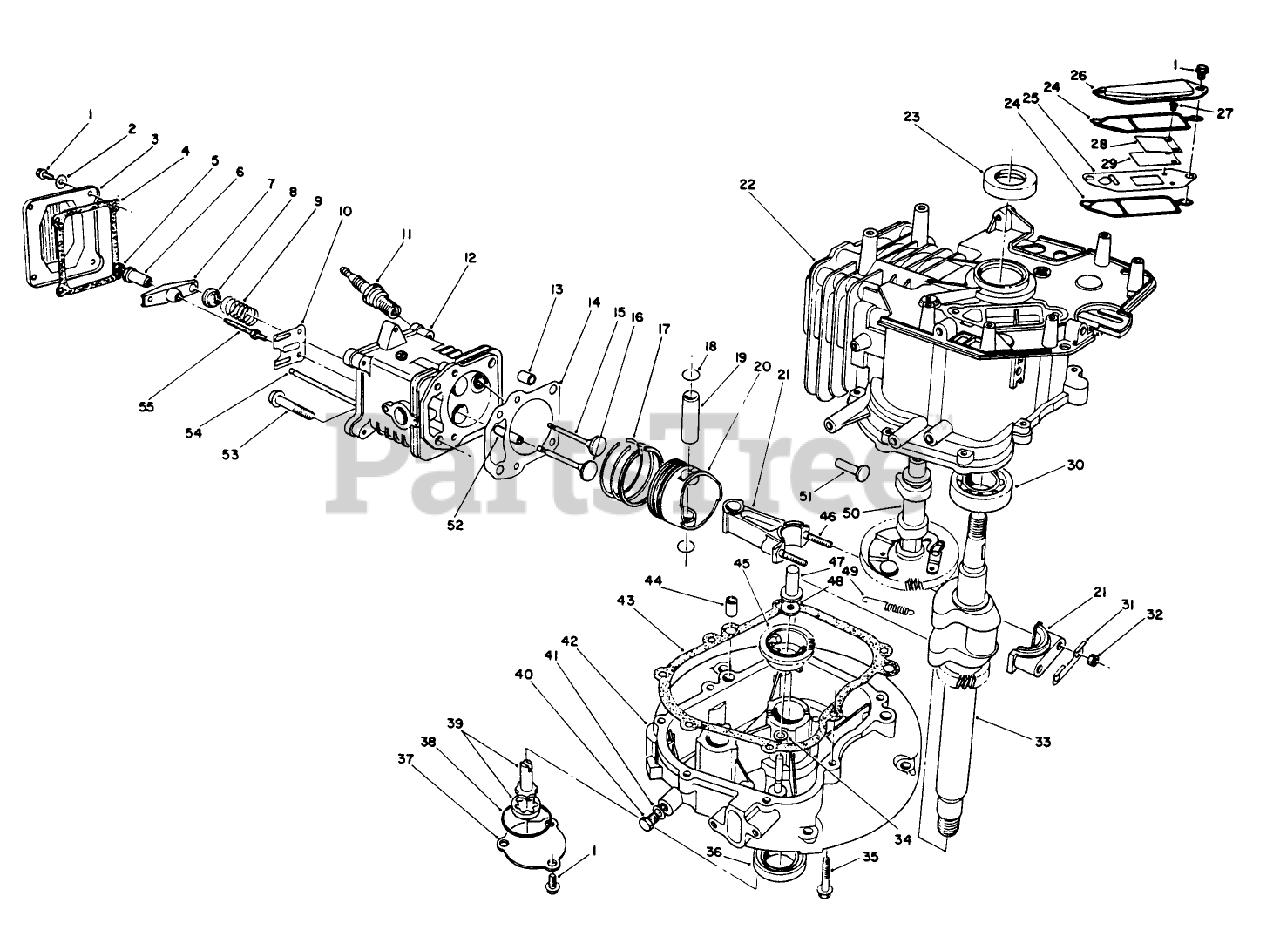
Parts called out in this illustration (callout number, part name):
2	WASHER
3	COVER
6	PIVOT
8	RETAINER
10	GUIDE
11	SPARK PLUG
12	CYLINDER HEAD
14	GASKET
16	VALVE-INTAKE
17	RING SET
22	ENGINE BLOCK
25	Plate Breather
27	Screw Reed Valve
28	Retainer Reed Valve
29	Valve-Reed
30	BEARING
33	CRANKSHAFT
37	COVER
38	O-RING
40	OIL DRAIN PLUG
41	GASKET
43	GASKET
47	PLUNGER
48	WASHER
50	CAMSHAFT
51	TAPPET
52	GUIDE
